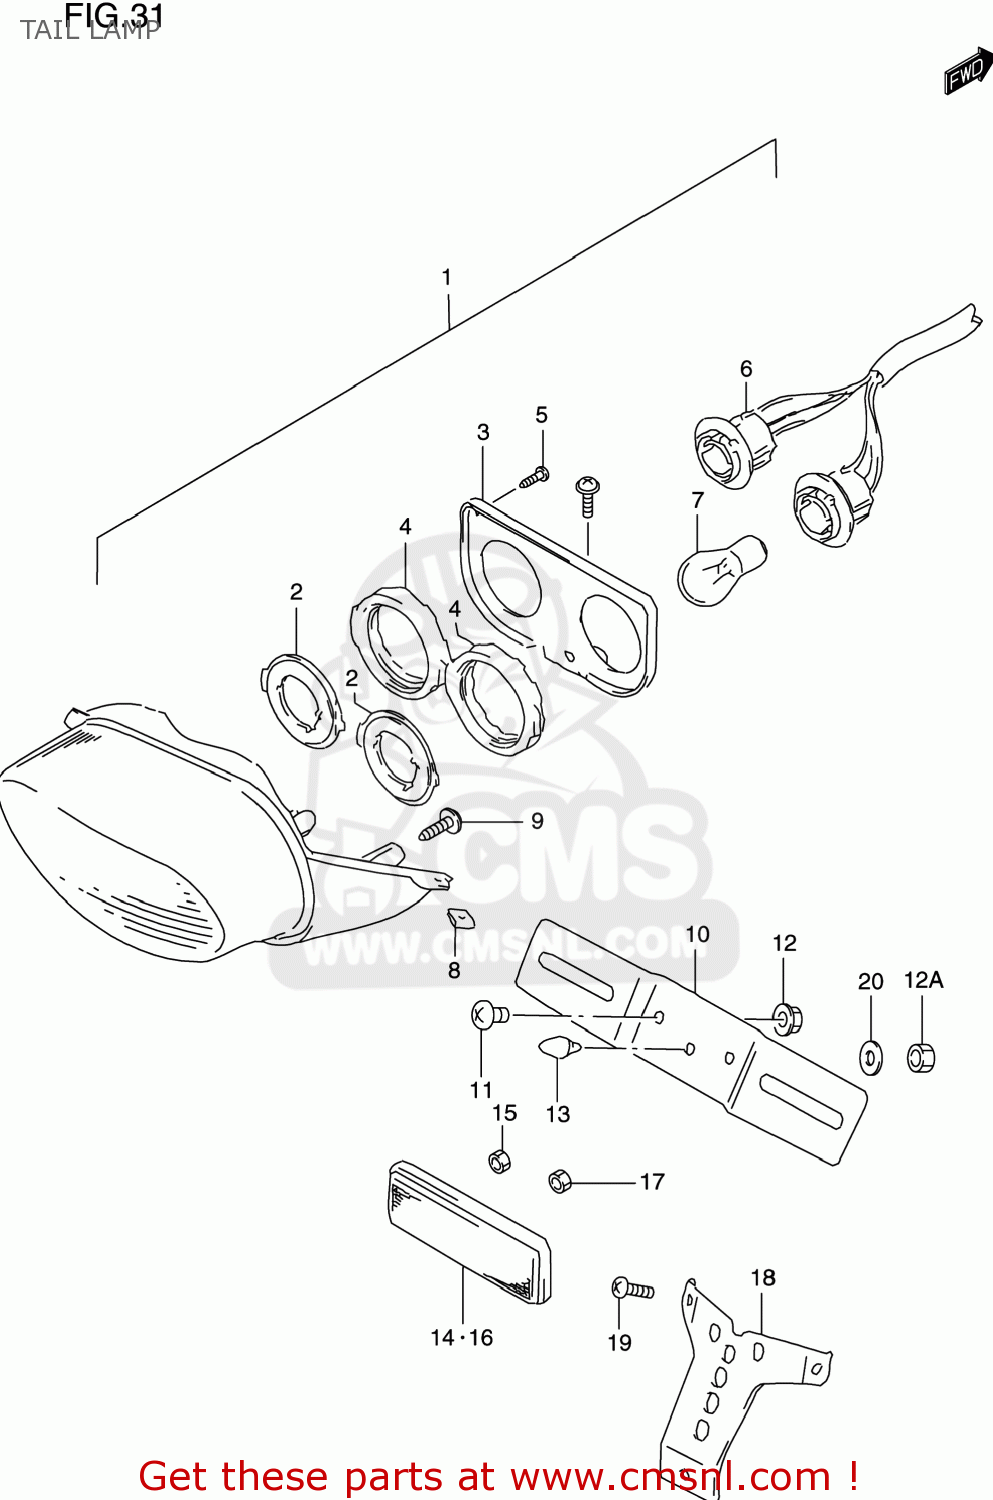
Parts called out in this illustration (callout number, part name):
1	LAMP ASSY,RR COMBINATION
2	PLATE NO.1
3	PLATE NO.2
4	CUSHION
5	SCREW
6	SOCKET & CORD
7	BULB(12V21/5W)
8	NUT
9	SCREW
10	BRACKET,LICENSE PLATE
11	SCREW 6X12
12	NUT
12A	NUT 6MM
13	CUSHION
14	REFLECTOR ASSY,RR
15	NUT
16	REFLECTOR ASSY,RR
17	NUT
18	BRACKET,RR REFLECTOR
19	SCREW(6X12)
20	WASHER(6.5X20X1.2)
